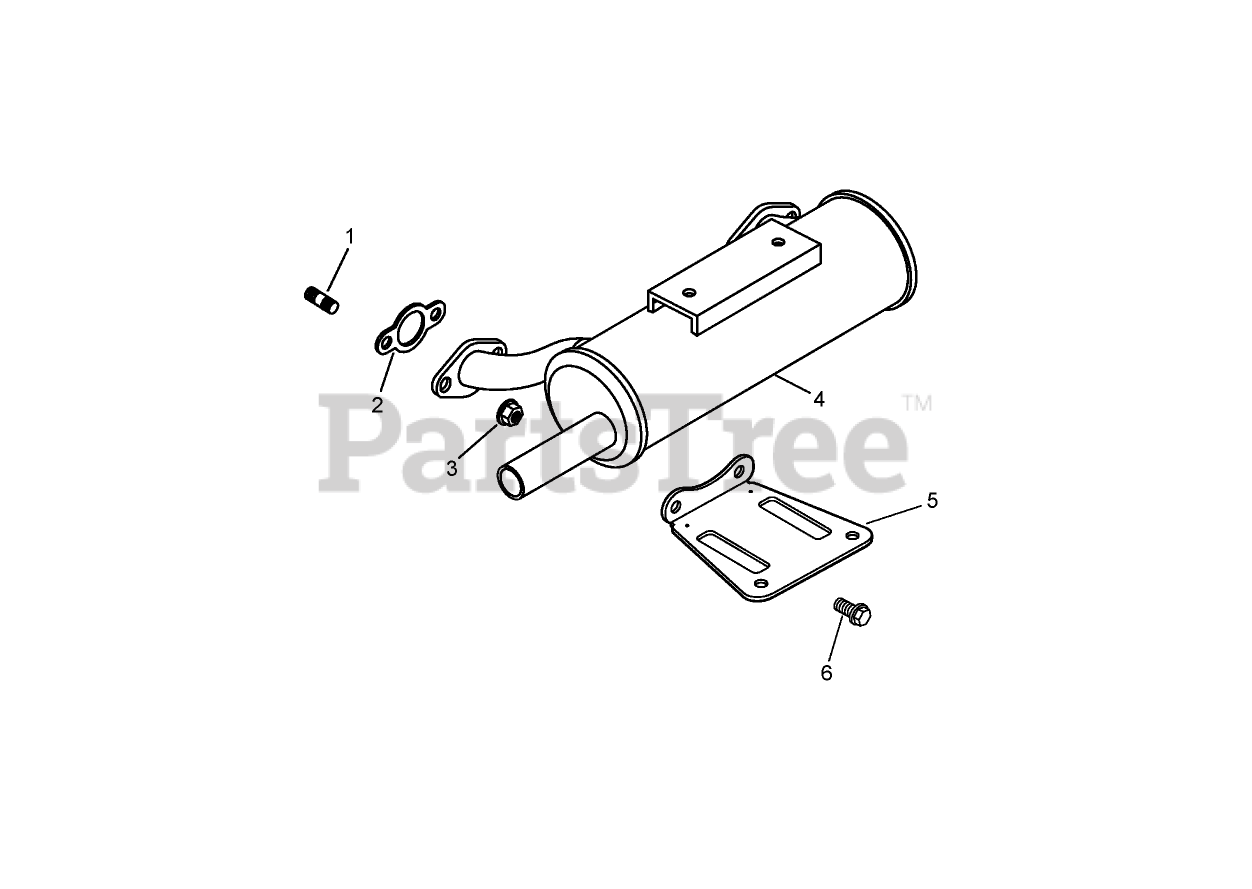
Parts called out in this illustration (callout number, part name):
1	STUD (M8X1.25X33)
2	GASKET-EXHAUST
3	NUT-FLANGE (M8X1.25)
4	Muffler
5	Bracket-Muffler
6	SCREW-HF (M8X1.25X20)
